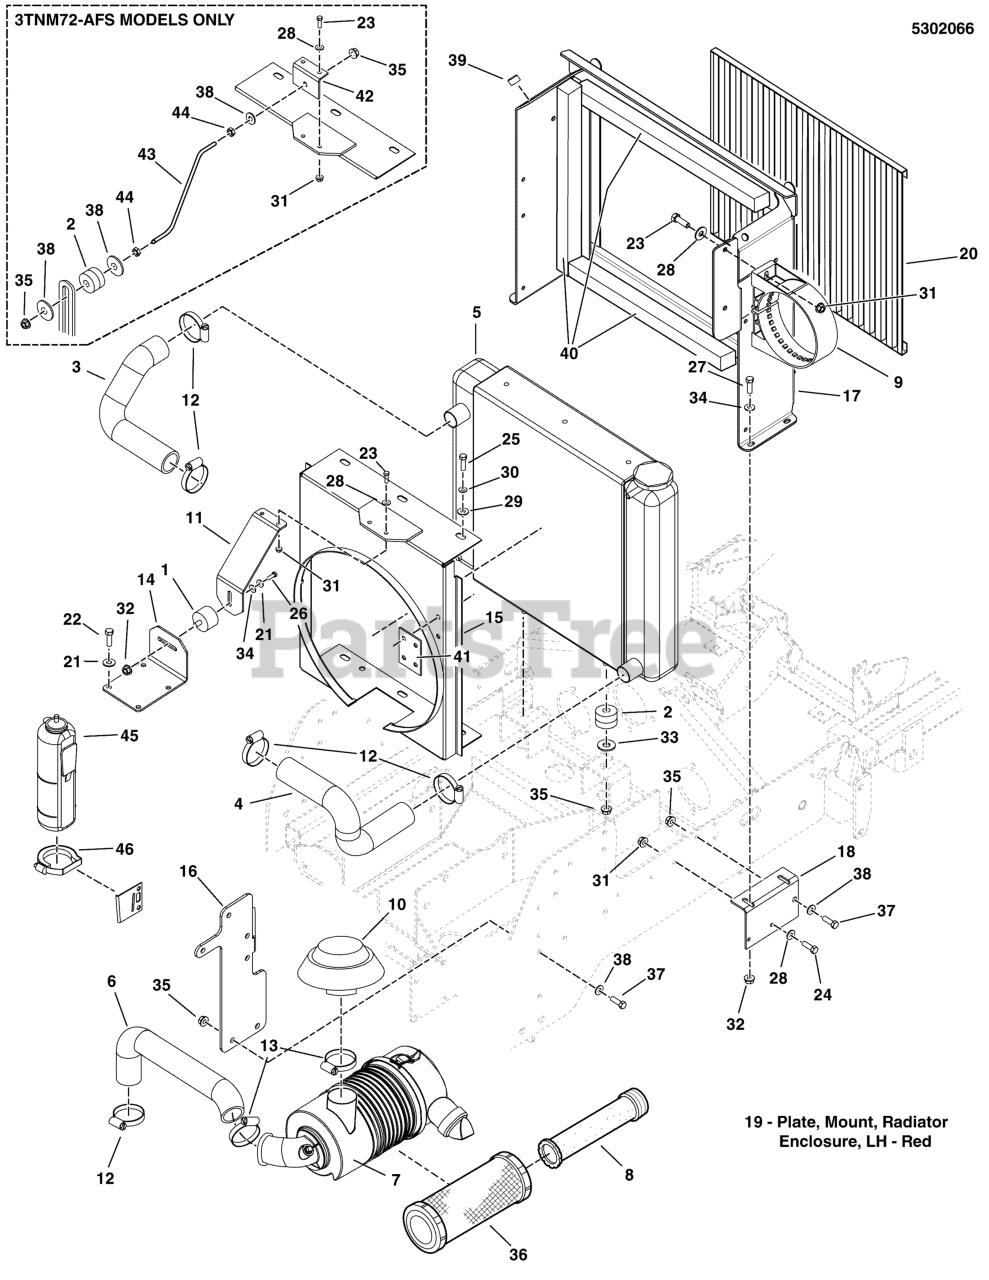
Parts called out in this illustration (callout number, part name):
1	MOUNT,ISO,TOP
2	MOUNT, ISO, BOTTOM
3	HOSE, UPPER, RADIATOR
4	HOSE, LOWER, RADIATOR
5	RADIATOR III, IS2500Z & S175X, YANMAR
6	HOSE, AIR CLEANER
7	AIR CLEANER ASSY
8	AIR FILTER, SMALL DIA., INT.
9	BRACKET, AIR CLEANER ASSY
10	CAP, A/C RAIN
11	MOUNT, UPPER RADIATOR
12	CLAMP, SS HOSE, 1-3/4
13	CLAMP, SS HOSE 2-3/4
14	MOUNT, UPPER ENGINE
15	WELD, SHROUD - BLK
16	BRACKET, AIR FILTER - RED
17	WELD, RADIATOR ENCLOSURE - RED
18	PLATE,MOUNT,RADIATOR ENCLOSURE, RH - RED
19	PLATE, MOUNT,RADIATOR ENCLOSURE,LH - RED
20	SCREEN, FRONT, RAD
21	WASHER, 5/16 LOCK CZ
22	BOLT, M8-1.25 X 20MM GD8.8
23	BOLT, 1/4-20 X 3/4 GD5 YZ
24	BOLT, 1/4-20 X 1" GD5 CZ
25	BOLT, 5/16-18 X 5/8 GD5 YZ
26	BOLT, 5/16-18 X 3/4 GD5
27	BOLT, 5/16-18 X 1 GD5 YZ
28	WASHER, 1/4 SAE
29	WASHER, 5/16 USS
30	WASHER, 5/16 INT. TOOTH LOCK
31	NUT, 1/4-20 HEX NYLOCK FLANGE
32	NUT, 5/16-18 HEX NYLOCK FLANGE
33	WASHER-3/8 FENDER
34	WASHER, 5/16" SAE
35	NUT, 3/8-16 HEX NYLOCK FLANGE
36	ELEMENT ASSY
37	BOLT, 3/8-16 X 1" GD5 CZ
38	WASHER, 3/8 SAE
39	MNT, VBRTN, RBBR
40	FOAM, 3/4 X 1 X 18
41	TAB, MOUNT, COOLANT TANK - BLK
42	BRACKET,RADIATOR TOP SUPPORT
43	ROD, RADIATOR SUPPORT
44	NUT, 3/8-16 HEX SERRATED FLANGE
45	BOTTLE, COOLANT OVERFLOW (SV)
46	CLAMP, COOLANT OVERFLOW (SV)
